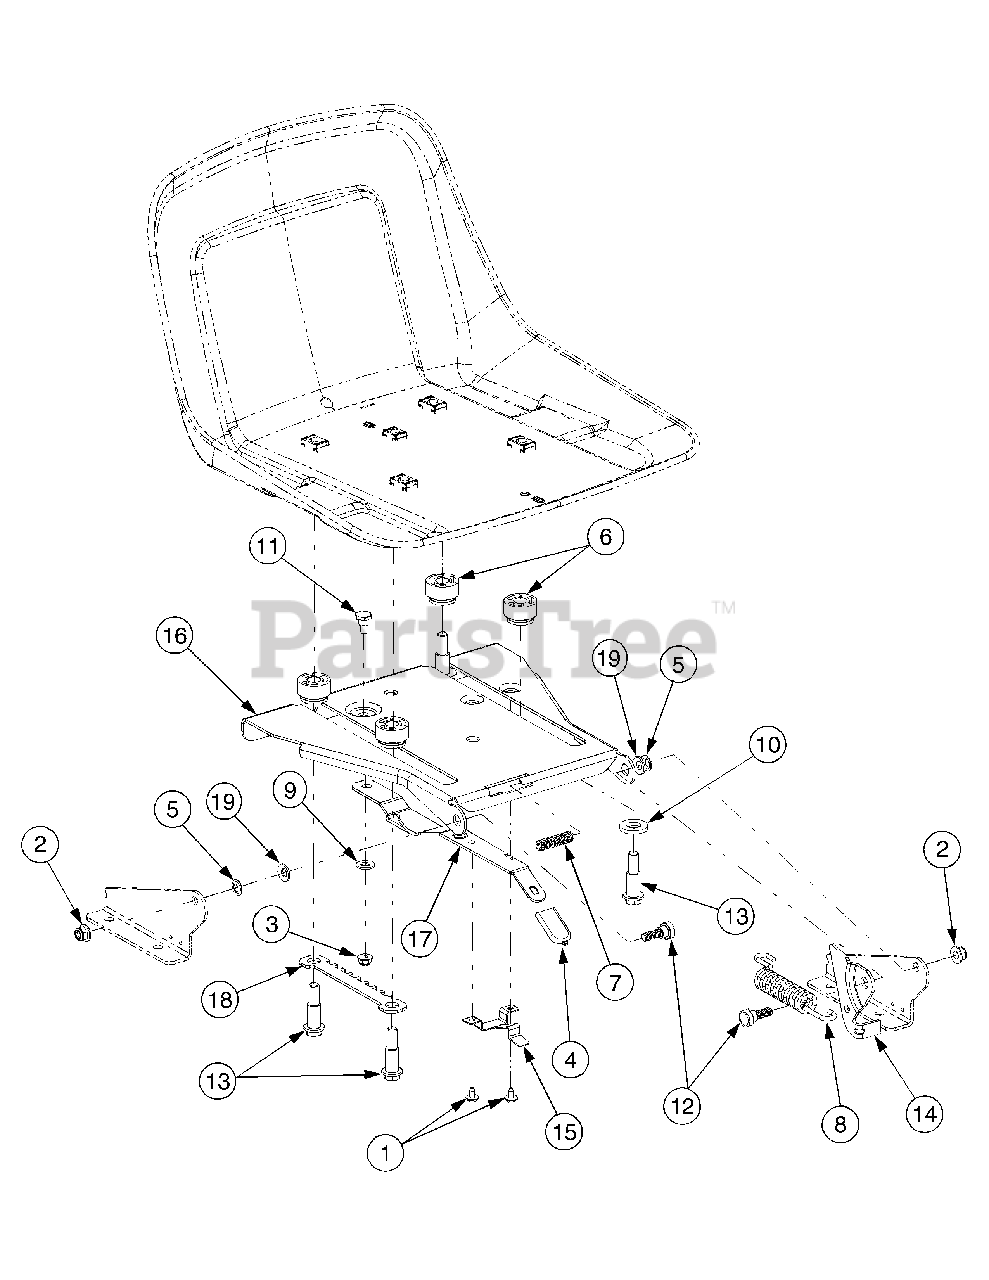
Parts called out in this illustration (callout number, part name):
1	Screw, Hx. Wash. Hd. Tapp #10-16 x .375
2	Nut, Hx Insert Flange Lck, 5/16-18 GrF
3	Nut, Hx Insert Flnge Lck, 1/4-20 GrF
4	Grip, Seat Adjustment
5	Nut, Speed, .3125
6	Spacer, Seat Adjustment
7	Spring, Compression, .41 x 1.5
8	Spring, Extension, .84 Dia. x 4.6
9	Washer, Flat, .344 x .62 x .033
10	Washer, Flat, .531 x 1.062 x .134 HT
11	Screw, Shoulder, .34 x .285:1/4-20
12	Screw, Shoulder,.437 x .268:5/16-18
13	Screw, Shoulder, .5 x .925:3/8-16 ..
14	Bracket, Seat Lift
15	Stop, Seat Adjustment
18	Index Bracket, Seat Adjustment
19	Washer, Belleville, .34 x .872 x .06
